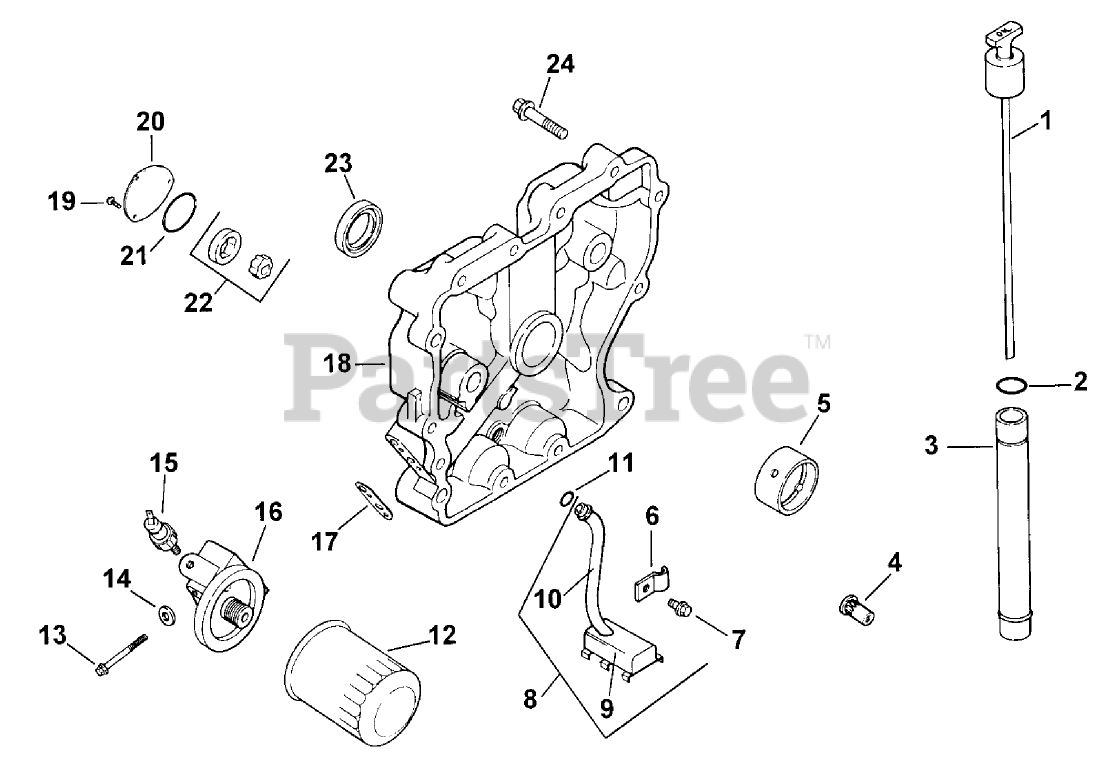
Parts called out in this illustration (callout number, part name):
1	Dipstick
2	O-Ring
3	Tube, oil fill
4	Valve-Oil Pressure
5	Bearing, crankshaft
6	Clip
7	Screw M5x0.8x16 (Only On: 72042, 72063, 72062, 72043)
8	Kit, oil pick-up (Includes 9, 10)
9	Pick-up, oil screen
10	Tubing, oil pick-up
11	O-Ring, oil pick-up
12	Filter-Oil
13	Screw, hex. flange M6x1.0x60
14	Washer
15	Swutch, oil pressure
16	Adapter, oil filter
17	Gasket, oil filter adapter
18	Plate, closure Asm (Includes 4,5,19-22)
19	Screw M5x0.8x16 (Only On: 72042, 72063, 72062, 72043)
20	Cover, oil pump
21	O-Ring, oil pump cover
22	Pump-Oil (Only On: 72042, 72063, 72062, 72043)
23	Seal-Crankshaft (Only On: 72042, 72043, 72062, 72063)
24	Screw
24	Screw M8x1.25x45 (Only On: 72103, 72083)
